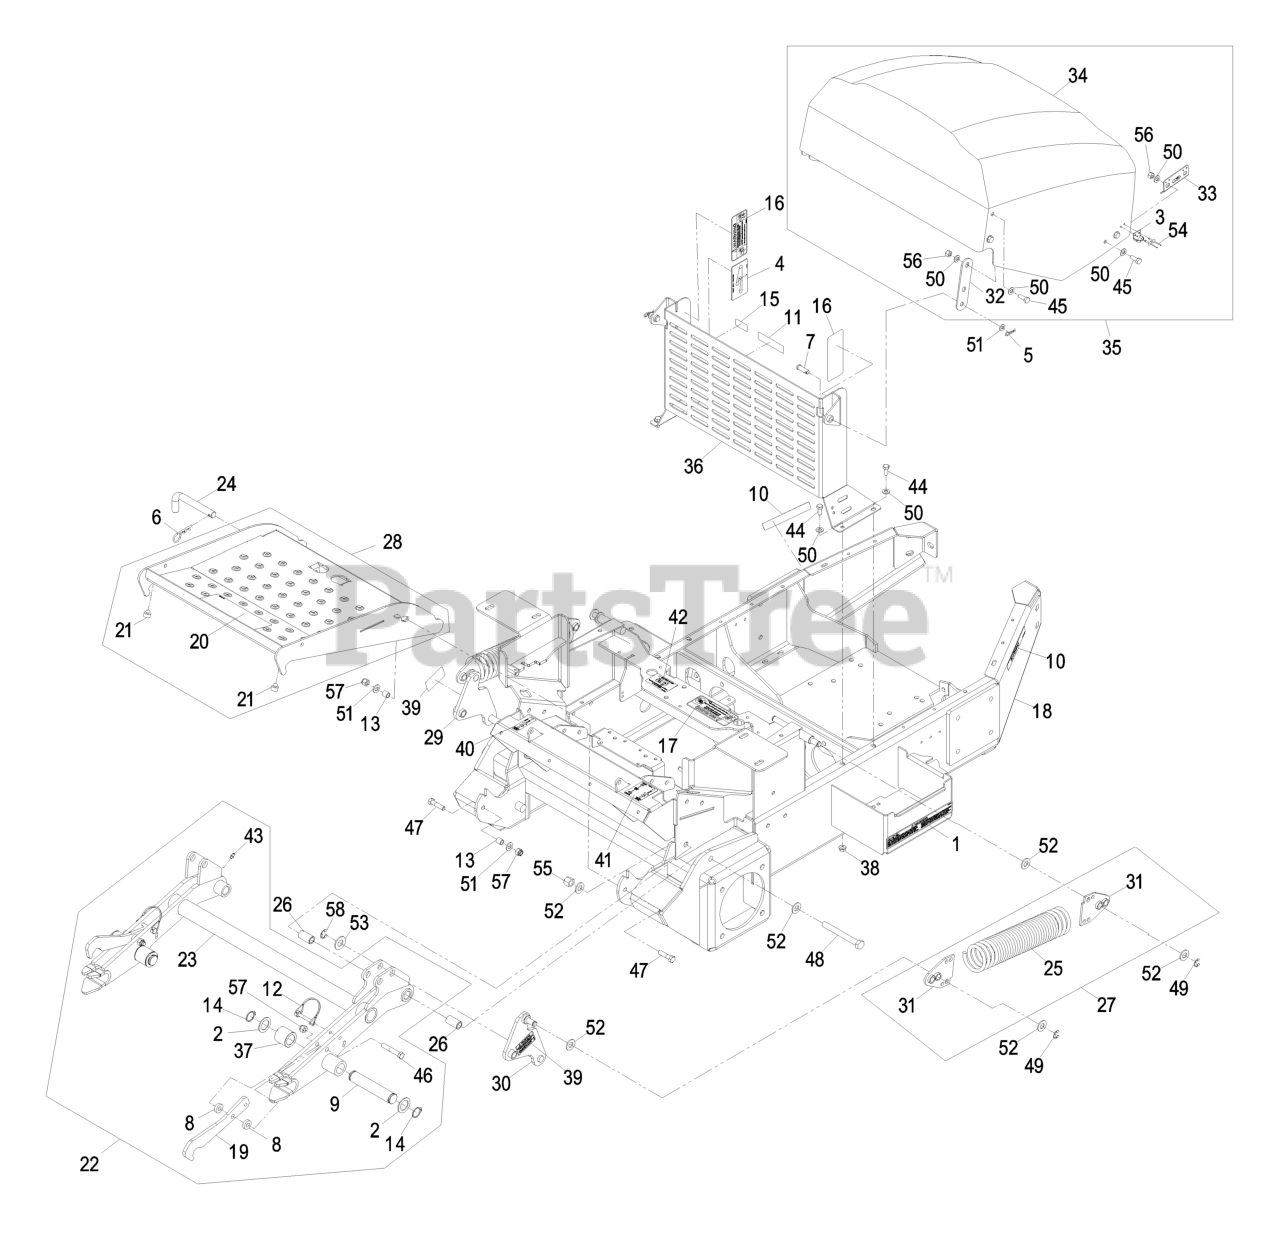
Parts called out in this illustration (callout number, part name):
1	DECAL-BATTERY
2	WASHER-SPACER
4	DECAL-ROUTING, BELT
5	PIN-COTTER
6	PIN-COTTER
7	PIN-CLEVIS
8	SPACER
10	DECAL-WARNING
11	DECAL-COVER, MISSING
12	PIN-HITCH
13	SPACER-TUBE, PUMP LINK
14	RING-RETAINING
16	DECAL-DEVICES, ROTATING
17	DECAL,PUMP FAN WARNING
19	LATCH, FMZ HITCH (PLATED)
20	DECAL-WARNING
21	BUMPER-RUBBER
22	ASM,HITCH FMZ
24	PIN,FULL FOLD (PLTD)
25	SPRING,EXTENSION (PLATED)
26	BUSHING,HITCH PIVOT
27	ASM,FMZ WT XFR SPRING
29	ASM,FMZ RH SPRING BELLCRA
30	ASM,FMZ LH SPRING BELLCRA
31	WLD,FMZ SPRING ANCHOR (PL
33	HOOK, HOOD
34	DECAL,FRONTRUNNER
35	ASM,FMZ AC HOOD W/DCL COM
36	ASM,FMZ A/C HOOD SUPPORT
37	ROLLER,LOCK LEVER
39	DECAL,SPRING LOADED
40	DECAL-CONTROL, MOTION
41	DECAL,MOTION CNTL/PARK BR
42	DECAL,PUMP DRIVE RELEASE
43	FITTING-GREASE
44	SCREW-HH
45	SCREW-HH
46	SCREW-HH
47	SCREW-HH
48	SCREW-HH
49	RING-RETAINING, EXTERNAL
50	WASHER-PLAIN
51	WASHER-FLAT
52	WASHER-FLAT
53	WASHER-FLAT
55	NUT-LOCK, NI
56	NUT-LOCK, NI
57	NUT-LOCK, NI
